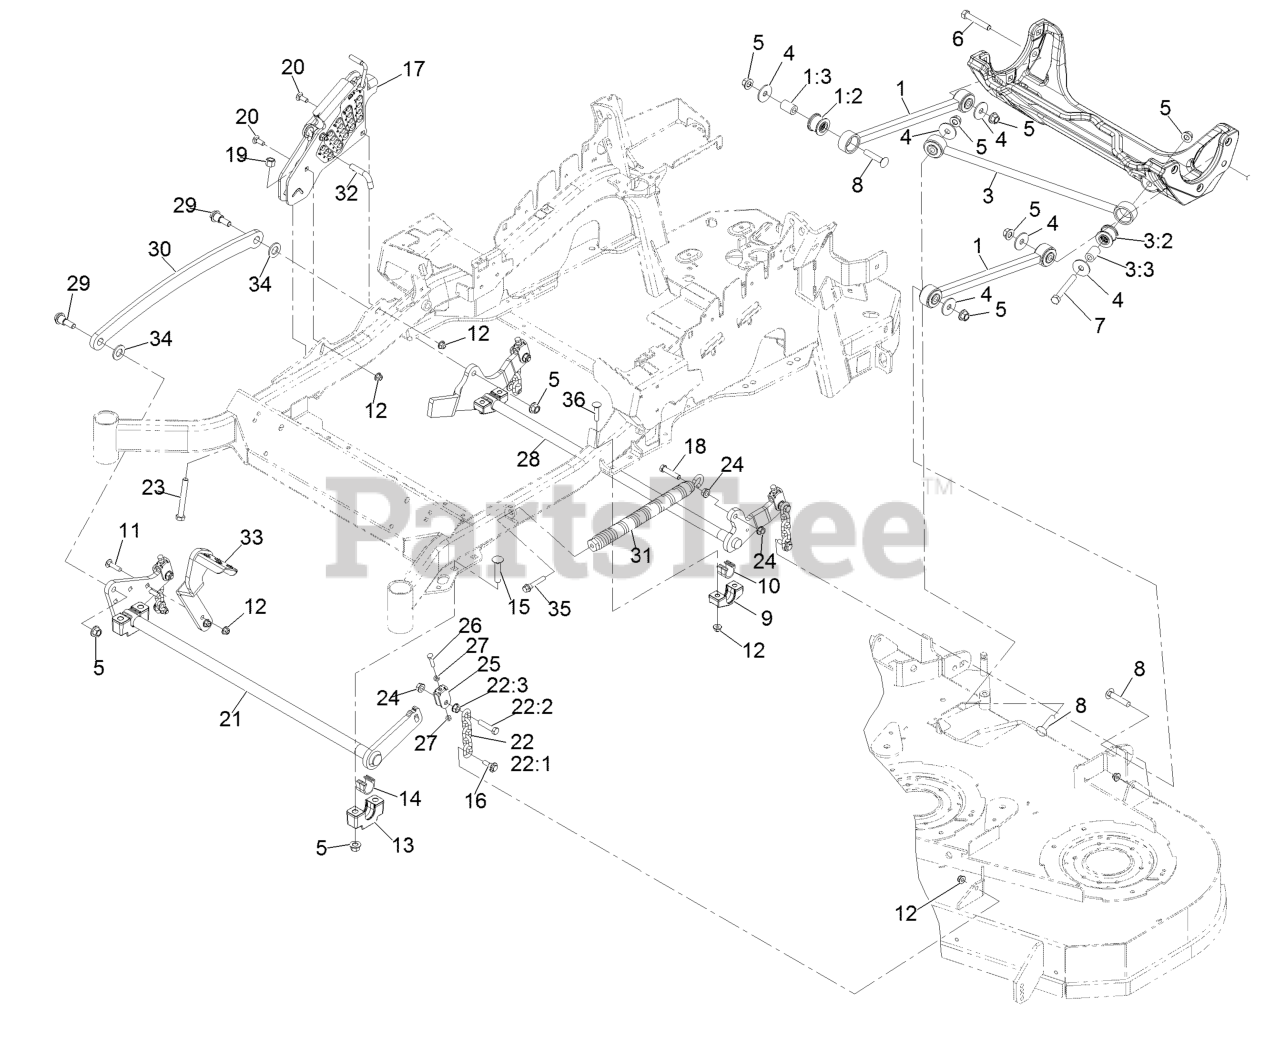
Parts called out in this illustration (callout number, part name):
1	LONG STRUT ASM
1:2	BUSHING-SUSPENSION, RUBBER
3	PANHARD ROD ASM
3:2	BUSHING-SUSPENSION, RUBBER
4	WASHER-THRUST
5	Nut-Lock 1/2-13
6	SCREW-HH
7	SCREW-HH
8	SCREW-CARR
9	SUPPORT-CROSS SHAFT, BEARING REAR
10	BEARING-CROSS SHAFT, REAR
11	SCREW-CARR
12	NUT-HF, NI
13	SUPPORT-CROSS SHAFT, BEARING
14	BEARING-CROSS SHAFT, FRON
15	Bolt-Carriage 1/2-13 X 2 1/2 Spl Neck
16	SCREW-SHOULDER, HHF
17	HOC ASM
18	SCREW-HH
19	NUT-LOCK, NI
20	BOLT-CARR
21	DECKLIFT-FRONT
22	DECK LIFT CHAIN ASM
22:1	CHAIN-LIFT, DECK
22:2	SCREW-HH
23	BOLT-TAP
25	YOKE-ADJUST, DECK
26	SCREW-HH
27	NUT-JAM
28	LIFT-DECK, REAR
29	SCREW-SHOULDER, HHF 1/2-13 X 1.12
30	LINK-LIFT, DECK
31	SPRING-EXTENSION
32	PIN-HOC
33	LEVER-FOOT
34	WASHER-FLAT
35	BOLT-SHOULDER
36	Bolt-Carriage 3/8-16 X 2 1/4
